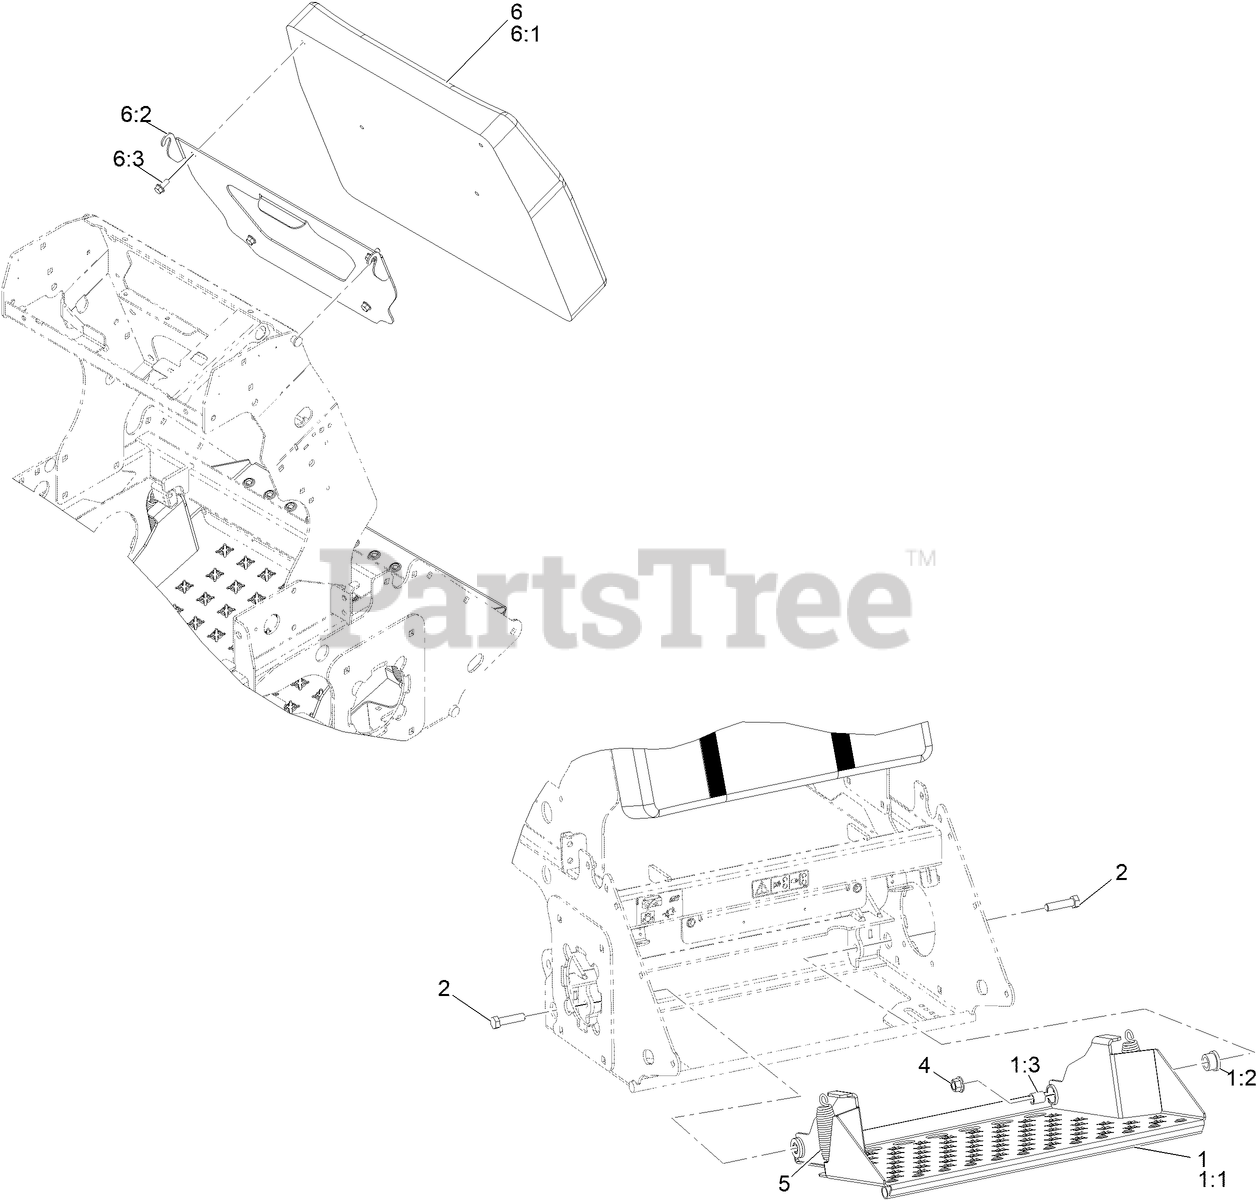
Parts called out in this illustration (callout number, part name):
1	ASM-OPERATORS PLATFORM
1:1	ASM-OPERATOR PLATFORM
1:2	BUSHING-RUBBER
2	SCREW-HH
4	Nut-Lock 1/2-13
5	SPRING-EXTENSION
6	ASM-THIGH PAD
6:1	PAD-THIGH
6:2	PLATE-HINGE-THIGH PAD
6:3	SCREW-HHF
